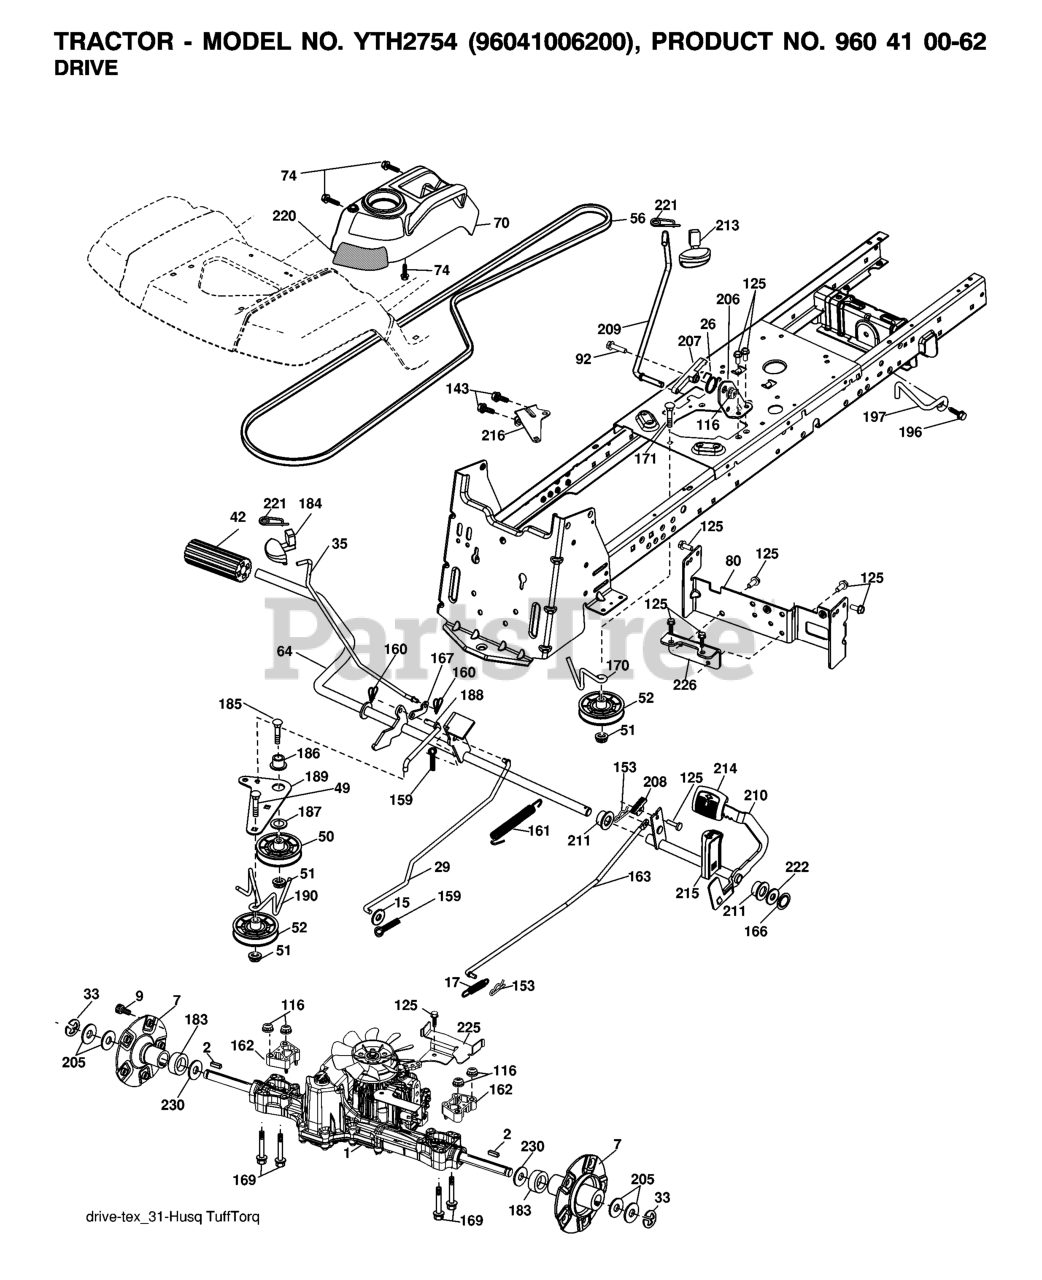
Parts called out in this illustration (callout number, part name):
2	KEY.SQUARE.187X2.500
7	HUB.ASM.WHEEL.REAR.22"
9	HUB BOLT
15	WASHER
17	SPRING.BRAKE.K46
26	SPRING.RETURN.CRUISE
29	ROD.BRAKE.K46
35	ROD.BRAKE.PARKING.GT.H
42	PEDAL COVER T
50	IDLER.FLAT.910.OFFSET
51	NUT LOCK FLG 3/8-16 UNC
52	IDLER.V-GROOVE.910.OFFSET
56	V-BELT.MOWER.92.40.42/K46
64	SHAFT.ASM.PEDAL.BRK.CNTR
70	RP CONSOLE.ASM.PCH.W/TB
74	SCREW.HI-LO.CONSOLE
80	STRAP.TORQUE.HG3000/K46
92	BOLT
116	NUT LOCK HEX FLANGE 5/16-18
125	SCREW
143	Screw 5/16-18 x 1/2 Hex, Self Tapping 5/16-18 x 1/2
153	RETAINER M
159	COTTER PIN
160	RETAINER CLIP
161	SPRING.RETURN.CLUTCH.2006
162	SPACER.TRANSAXLE.18&22
163	ROD.CONTROL.PEDAL.K46
166	NUT.PUSH.625.2006
167	LATCH.BRAKE.SPRING
170	KEEPER.V-IDLER.CENTER.
171	BOLT
183	SPACER.SPLIT.800X.350
184	HANDLE.PARKG.BRK.HUSQ X667
185	BOLT
186	SPACER.RETAINER
187	WASHER 12/32X2X10GA
188	RP.LINK.CLUTCH.GROUND.DRIVE
189	BELLCRANK.GROUND.DRIVE.TEX.
190	KEEPER.BELLCRANK.DRIVE
196	SCREW 3/8-16X1
197	BRKT.ANIT-ROTATION.CLUTCH
206	BRKT.MOUNT.LATCH.CRUIS
207	LATCH.CONTROL.CRUISE
208	GEAR.SECTOR.CONTROL.CR
209	ROD.CONTROL.CRUISE.GT.
210	ROCKER.ASM.PEDAL.CONTR
211	BEARING.NYLON
213	KNOB.CONTROL.CRUSIE.HU
214	PEDAL.FORWARD.TEX.GT.4
215	PEDAL.REVERSE.TEX.GT.4
216	BRACKET.PULLEY.IDLER.W/TEX
220	REFLECTOR.RH.TEX GT
221	RETAINER.SPRING.CLIP.H
222	WASHER
225	KEEPER.BELT.TRANSAXLE.K46
226	BRKT.MOUNT.TORQUE.K46.
230	WASHER.HARDENED
